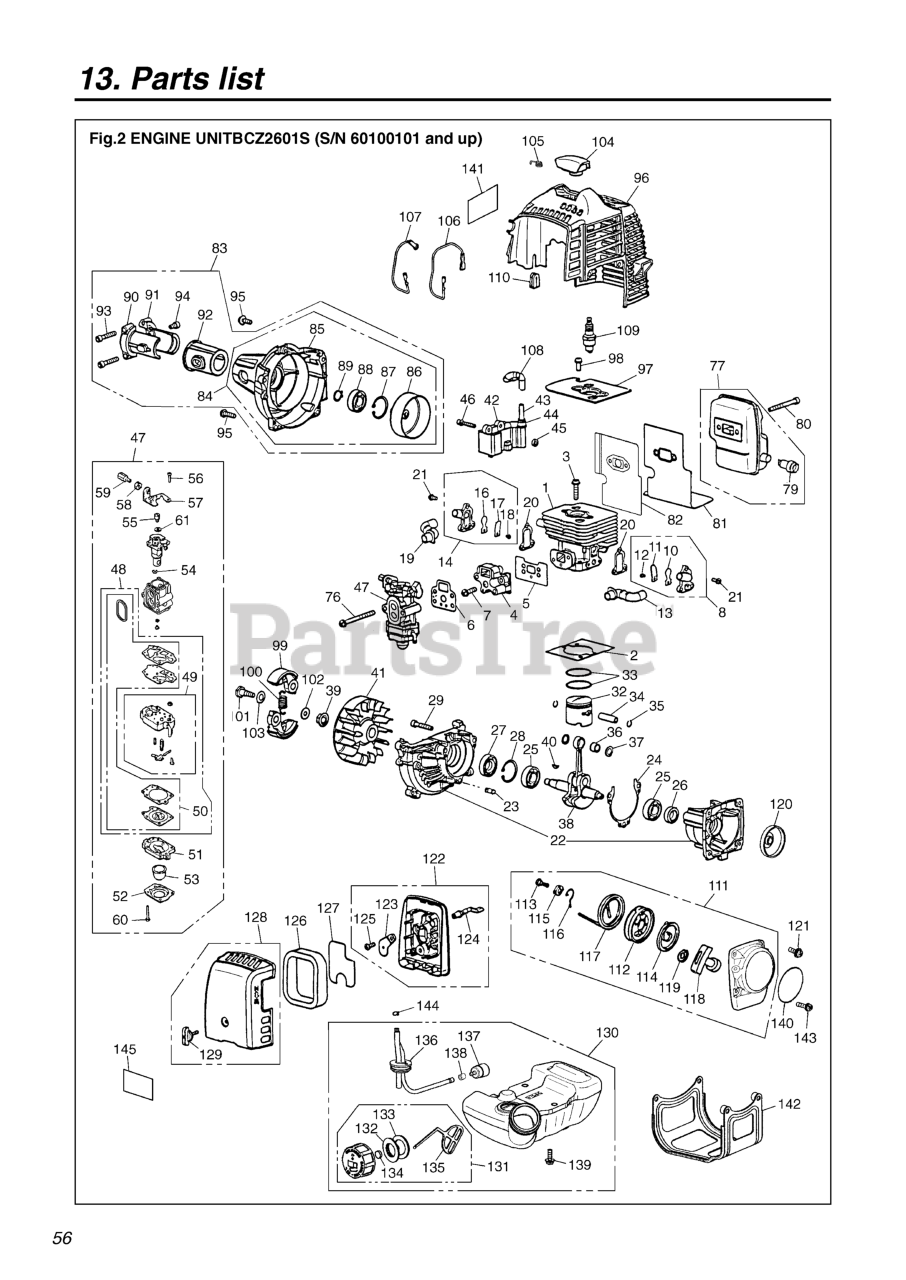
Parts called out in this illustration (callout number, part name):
1	CYLINDER
2	GASKET
3	BOLT
4	INSULATOR
5	GASKET, INSULATOR
6	GASKET, CARBURETOR
7	BOLT (RPLS 2850-14220)
8	REEDVALVE ASSY S
10	REEDVALVE
11	STOPPER
12	SCREW, M3 x 8
13	PIPE, AIR S
14	REEDVALVE ASSY F
16	REEDVALVE
17	STOPPER
18	SCREW, M3 x 8
19	PIPE, AIR F
20	GASKET, VALVE
21	SCREW
22	CRANKCASE-C
23	PIN
24	GASKET
25	BEARING
26	SEAL
27	SEAL, OIL (RPLS 1140-21220)
28	RING, SNAP, M28 x 1.2
29	BOLT
32	PISTON
33	RING, PISTON
34	PIN
35	RING, SNAP (RPLS 1101-41320)
36	BEARING (RPLS 1140-41330)
37	WASHER
38	CRANKSHAFT COMP
40	KEY
41	ROTOR
42	COIL-A
43	CORD
44	CAP
45	SPACER (RPLS -71260)
46	BOLT TORX
47	CARBURETOR
48	REBUILD KIT
49	BODY, PUMP
50	KIT, GASKET (REPLACES-06020)
51	BODY, PURGE
52	COVER, PUMP
53	PUMP, PRIMING
54	RING
55	SWIVEL
56	SCREW
58	NUT, CABLE ADJUSTER
59	SCREW, CABLE ADJUSTER
60	SCREW
61	WASHER
76	BOLT
77	MUFFLER-A
79	ARRESTER
80	BOLT
81	GASKET
82	PLATE, MUFFLER
83	COVER ASSY
84	COVER COMP. (REPLACES -31101)
85	COVER, FAN (REPLACES -31110)
86	DRUM (REPLACES 4810-31122)
87	RING, SNAP, M28 x 1.2
88	BEARING
89	RING, SNAP (RPLS 3130-13270)
90	BRACKET (A) (RPLS -31210)
91	BRACKET (B) (REPLACES -31220)
92	CUSHION
93	BOLT
94	BOLT
95	BOLT, TORX
96	COVER, ENGINE
97	PLATE
98	BOLT
99	SHOE
100	SPRING
101	BOLT
102	WASHER, FLAT (USE 182303)
103	WASHER (RPLS -51241)
104	CAP (RPLS 4810-72110)
105	SPRING
106	CORD (BLACK)
107	CORD, EARTH (RED)
108	TUBE
110	GROMMET
111	RECOIL ASSEMBLY
112	REEL
113	SCREW
114	SPRING, SPIRAL
115	COLLAR
116	ARM
117	ROPE (REPLACES 4500-75160)
118	KNOB (RPLS -75420)
119	PLATE, STOPPER
120	PULLEY
121	BOLT
122	BODY ASSEMBLY
123	PLATE, CHOKE
124	LEVER, CHOKE
125	SCREW
126	ELEMENT
127	SCREEN
128	COVER ASSEMBLY
129	KNOB (RPLS -82220)
130	TANK ASSY
131	CAP ASSY (RPLS -85201)
132	HOLDER (REPLACES -85230)
133	PACKING
134	FILTER
135	STOPPER
136	PIPE COMPLETE
137	FILTER ASSY
138	CLIP (REPLACES 2841-31280)
139	BOLT
140	LABEL, RECOIL
141	LABEL, COVER
142	GUARD (RPLS 4810-31911)
143	BOLT
144	CLIP
